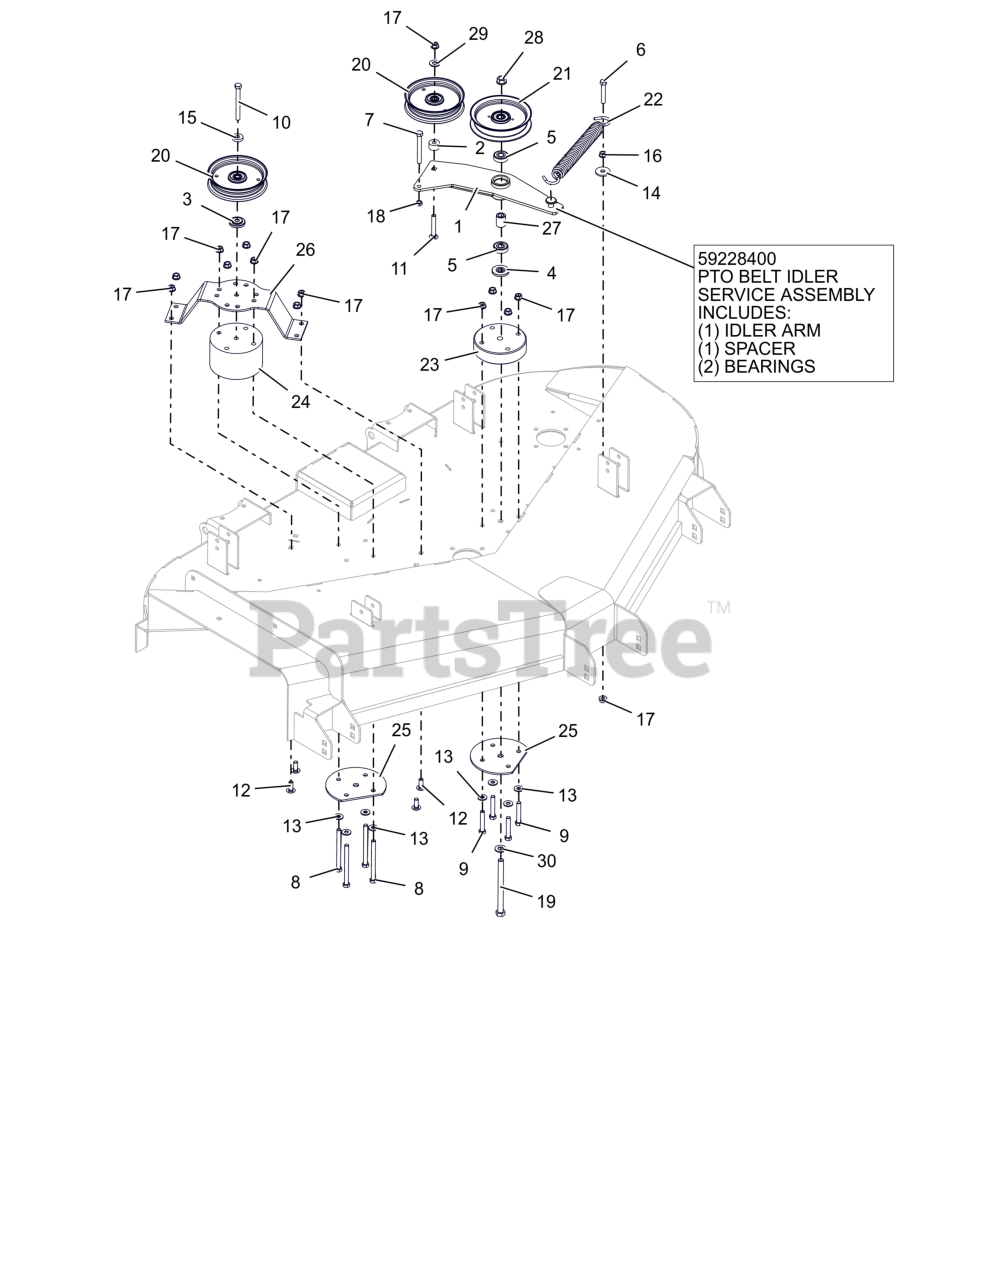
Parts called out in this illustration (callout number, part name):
1	WLDMT, IDLER ARM
1	PTO, IDLER ARM, ASSY
2	SPACER .390X1.000X.562
3	RETAINER, SHEAVE
4	SPACER, IDLER ARM
5	BRG-BALL .500X1.38X.437
6	BLT,HEX .38-16X2.25 G5 ZCC
7	BLT, HEX .38-16X3.25 G5 ZCC
8	BLT, HEX 0.375-16X4.5 GR8 ZCC
9	BLT, HEX 0.375-16X2.25 GR8 ZCC
10	BLT, HEX 0.375-16X3.75 GR8 ZCC
11	BLT,RHSN .38-16X2.50 G5 ZCC
12	BLT,RHSSN .38-16X1.00 G5 ZCC
13	WSHR,FLT .375X.875X.083 ZCC
14	WSHR,FLT .406X1.375X.135 ZCC
15	WSHR, FLT .390X1.00X.250 ZCC
16	NUT, SPNLK-FLG .38-16 G5 ZCC
17	NUT-LK-CTR-FLG .375-16 GF ZCC
18	NUT-JAM .375-16 G2 ZCC
19	BLT, HEX .50-13X6.00S G5 ZCC
20	PULLEY, FLAT IDLER .500 X .375 W/BRG
21	IDLER- FLAT - 5.000" X .750"
22	SPRING, EXTENSION
23	PEDESTAL, IDLER STAND OFF
24	PEDESTAL, IDLER STAND OFF
25	PLATE- REINFORCING - RED
26	BRACE, IDLER SUPPORT
27	SPACER .510 X .867 X 1.1485
28	NUT-LK-CTR-FLG .500-13 GG ZCC
29	WSHR,FLT .438X1.00X.083 ZCC
30	WSHR,FLT .531X1.062X.095 ZCC
